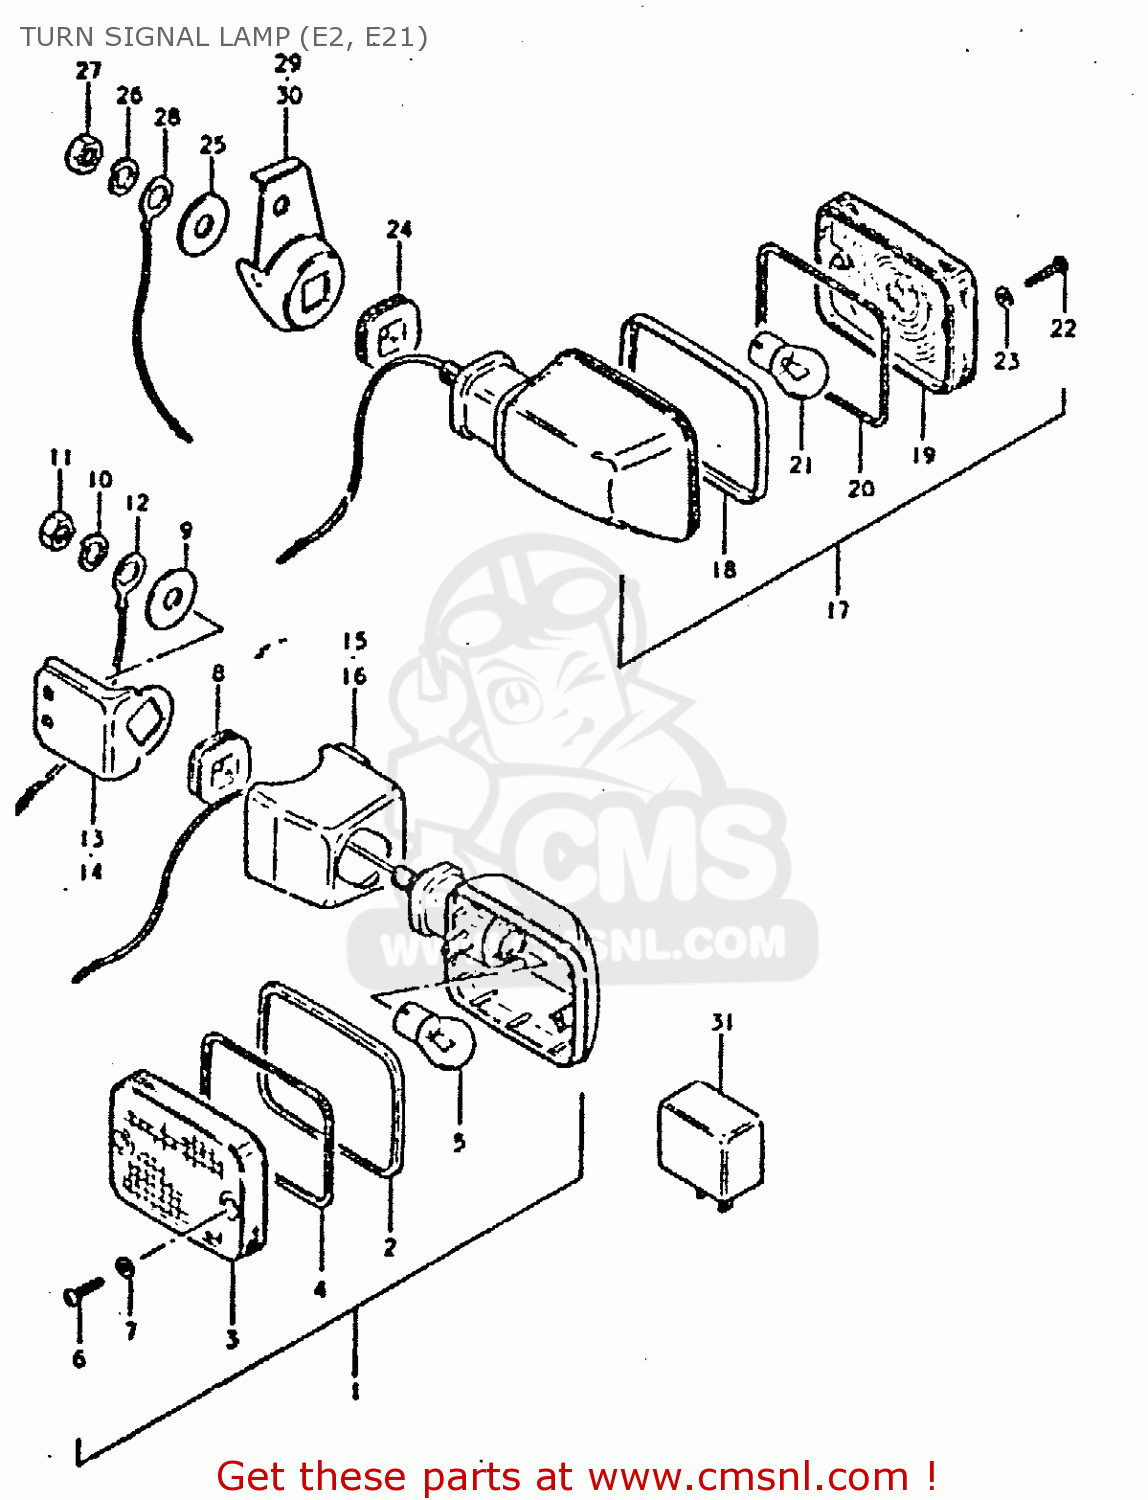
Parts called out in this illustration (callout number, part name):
1	LAMP, REAR TURN SIGNAL
2	RIM
3	LENS
4	GASKET (NAS)
5	BULB 12V 21W
6	SCREW
7	GASKET (NAS)
8	CUSHION
9	WASHER (10.5X30X2.3)
10	LOCK WASHER
11	NUT
12	WIRE,TURN SIGNAL LEAD
13	BRACKET,FRONT TURN SIGNAL
14	BRACKET,FRONT TURN SIGNAL
15	COVER,TURN SIGNAL BRACKET
16	COVER,TURN SIGNAL BRACKET
17	LAMP, REAR TURN SIGNAL
18	RIM
19	LENS
20	GASKET (NAS)
21	BULB 12V 21W
22	SCREW
23	GASKET (NAS)
24	CUSHION
25	WASHER (10.5X30X2.3)
26	LOCK WASHER
27	NUT
28	LEAD WIRE,EARTH
29	BRACKET,REAR TURN SIGNAL
30	BRACKET,REAR TURN SIGNAL
31	RELAY,TURN SIGNAL
